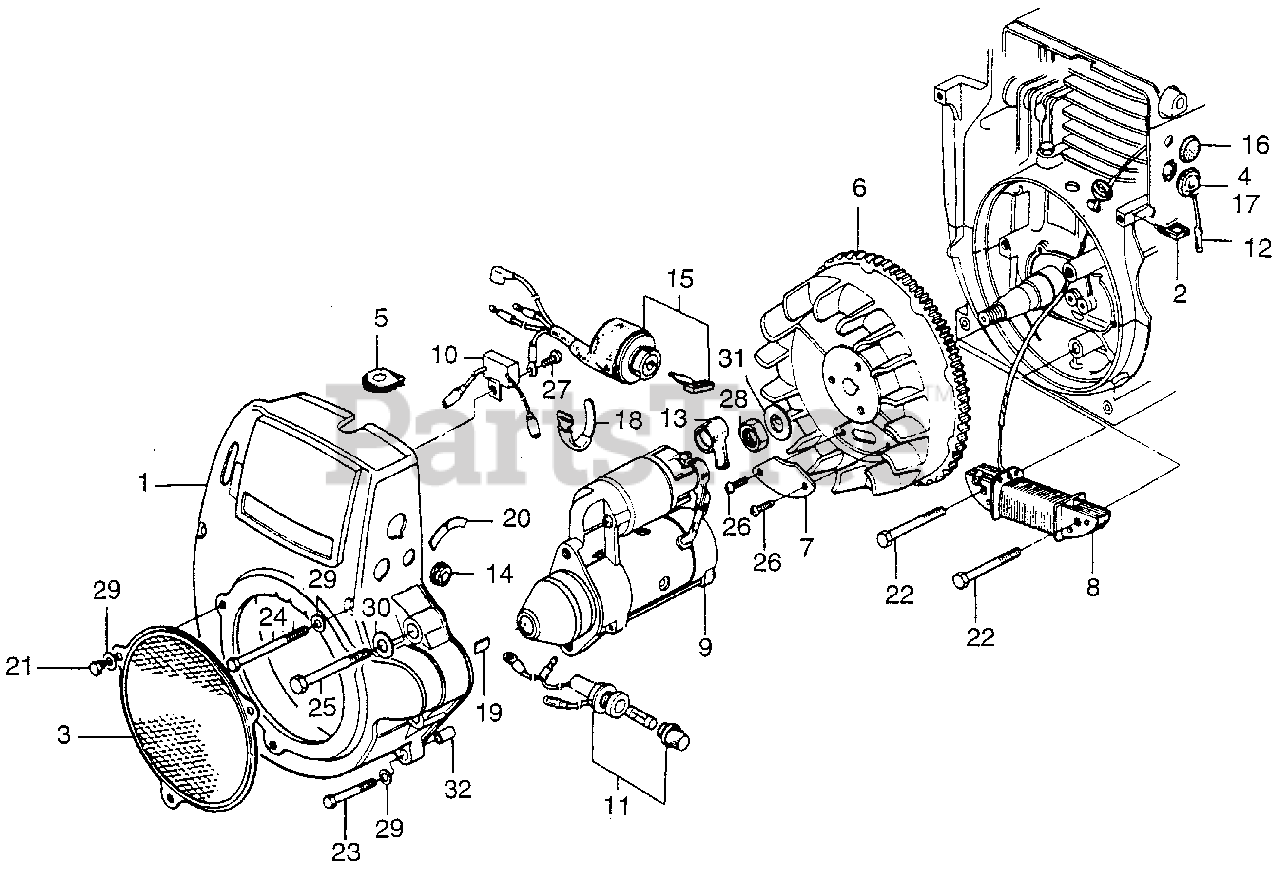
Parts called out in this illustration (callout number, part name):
1	COVER, FAN *R8* (BRIGHT RED)
2	MOUNT, SIDE COVER
3	PROTECTOR, FAN COVER *R8* (BRIGHT RED)
4	GROMMET, SIDE COVER
5	GROMMET, WIRE
7	COVER, FLYWHEEL WINDOW (NOT AVAILABLE)
8	COIL ASSY., CHARGE
9	MOTOR ASSY., STARTER (NOT AVAILABLE)
10	RECTIFIER, SILICON (NOT AVAILABLE)
11	HOLDER ASSY., FUSE
12	WIRE B, STOP SWITCH (NOT AVAILABLE)
13	COVER, STARTER MOTOR TERMINAL
14	GROMMET B, WIRE
15	SWITCH ASSY., COMBINATION (NOT AVAILABLE)
16	GROMMET A, SIDE COVER
18	BAND, CABLE
19	MARK, FUSE
20	MARK, ENGINE SWITCH
21	BOLT, HEX. (6X8)
22	BOLT, HEX. (6X28)
23	BOLT, HEX. (6X40)
24	BOLT, HEX. (6X70)
25	BOLT, HEX. (8X55)
26	SCREW, PAN (5X10)
27	SCREW, PAN (6X8)
28	NUT, HEX. (14MM)
29	WASHER, PLAIN (6MM)
30	WASHER, PLAIN (8MM)
31	WASHER, PLAIN (14MM)
32	PIN A, DOWEL (8X14)
